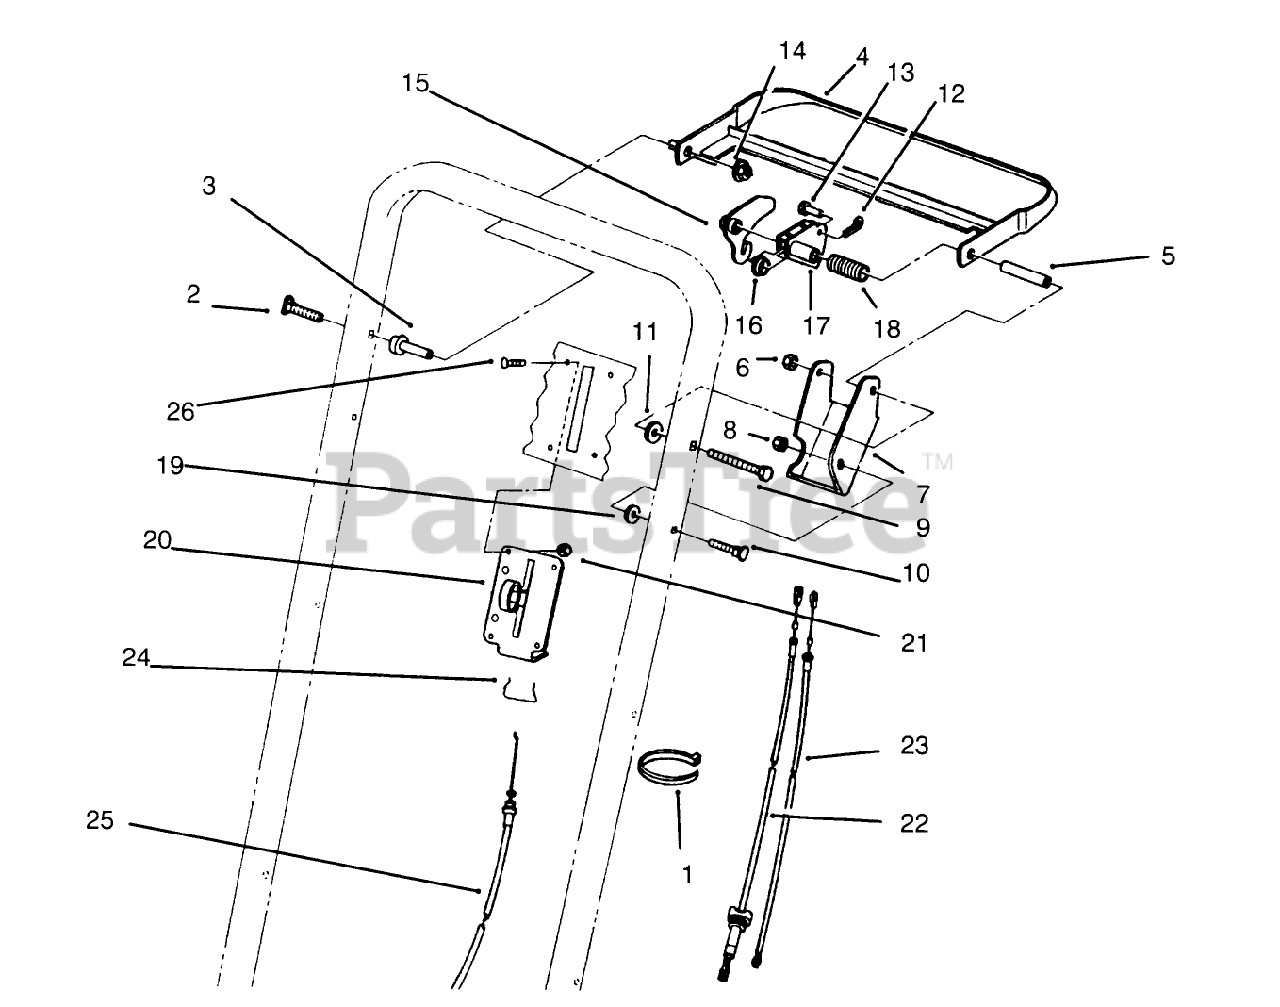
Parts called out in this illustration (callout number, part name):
1	TIE-CABLE
2	SCREW
3	SPACER-SUPPORT
5	SPACER-BRACKET, CONTROL
6	NUT-LOCK, NI
8	NUT-LOCK, NI
9	SCREW-HH
10	SCREW-HANDLE
11	SPACER
12	PIN-COTTER
13	PIN-CABLE
14	NUT-LOCK, NI
15	LEVER-TRACTION
16	BUSHING-FLANGE
17	LEVER-BBC
18	SPRING-CONTROL
19	SPACER
20	CONTROL-THROTTLE
21	NUT-LOCK, NI
22	CABLE-TRACTION
23	CABLE-CLUTCH
24	RETAINER-CABLE, THROTTLE
25	CABLE-THROTTLE
26	SCREW-PPH
